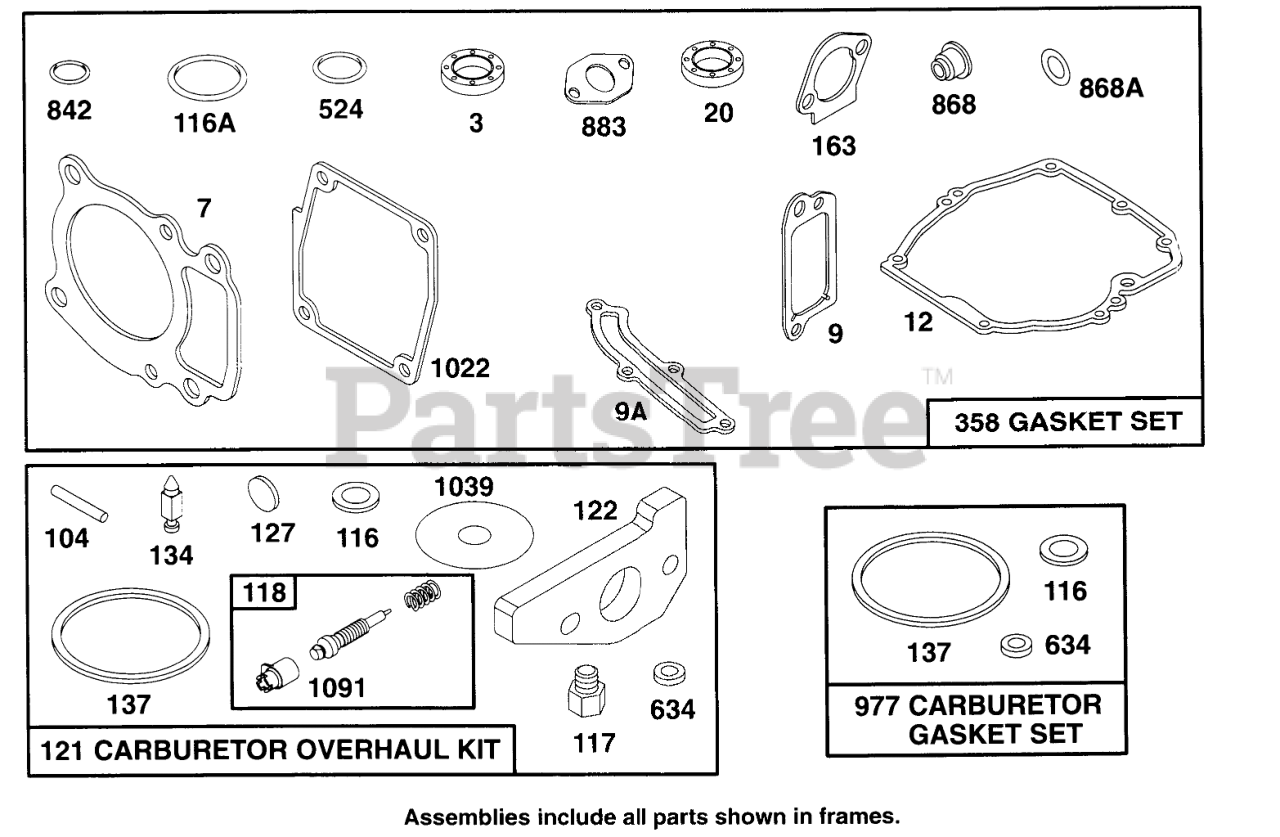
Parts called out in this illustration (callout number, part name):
3	SEAL - OIL
7	CYLINDER HEAD GASKET
9	BREATHER GASKET
9A	GASKET-BREATHER
12	ENGINE BASE GASKET
20	SEAL-OIL
104	FLOAT HINGE PIN
116	SEALING GASKET
116A	O RING SEAL
117	Jet-Main
118	VALVE/SPRING - NEEDLE
121	KIT-CARBURETOR OVERHAUL
122	ADAPTER ASSEMBLY
127	PLUG - WELCH
134	Valve-Inlet (Includes Seat)
137	FLOAT BOWL GASKET
163	AIR CLEANER GASKET
358	GASKET SET
524	O-RING
634	SEAL WASHER
842	O-RING
868	SealAssy-Valve
868A	Seal-Valve
883	EXHAUST GASKET
977	CARBURATOR GASKET SET
1022	ROCKER COVER GASKET
1039	FLOAT LIMITER
1091	CAP - LIMITER
